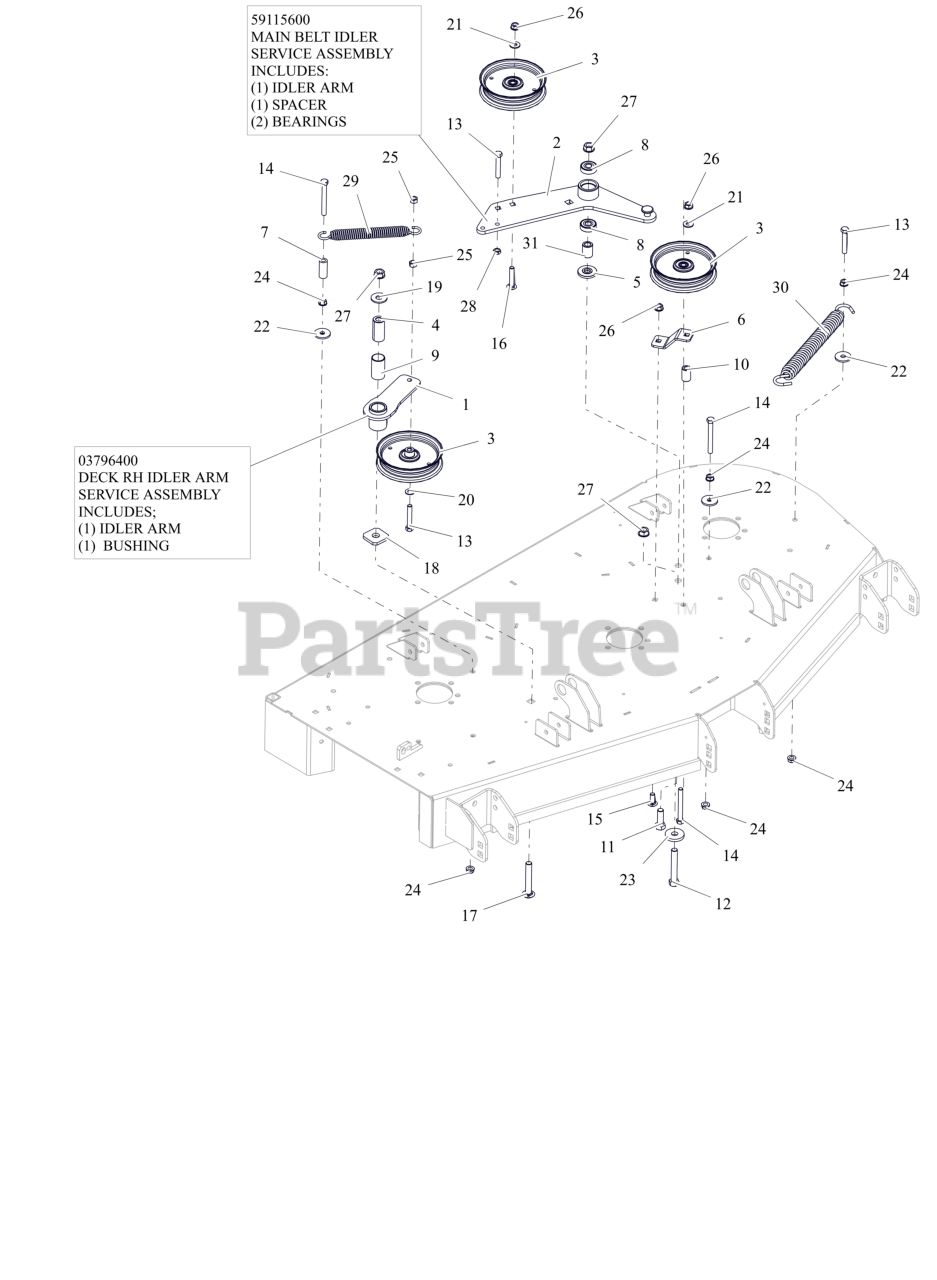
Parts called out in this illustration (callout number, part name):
1	WMT, IDLER ARM - BLACK
1	ASM, IDLER ARM (DECK)
2	WLDMT, DECK PTO IDLR ARM
2	ASSEMBLY, MAIN BELT IDLER
3	IDLER- FLAT - 5.00" X .75"
4	BSHG, SPCR .502X.997X2.03 PM
5	SPACER, IDLER ARM
6	PTO FIXED IDLER MTG BRKT-ORG
7	HOSE, .38 X 1.65
8	BRG-BALL .500X1.38X.437
9	BSHG, 1.00X1.125X1.937
10	BUSHING, SLV .380X.750X1.190
11	BLT,HEX .50-13X1.50 G5 ZCC
12	BLT,HEX .50-13X3.25 G5 ZCC
13	BLT,HEX .38-16X2.25 G5 ZCC
14	BLT, HEX .38-16X3.25 G5 ZCC
15	BLT,RHSSN .38-16X1.00 G5 ZCC
16	BLT,RHSSN.375-16X2.00 G5 ZCC
17	BTL,RHSSN .500-13 X 3.25 G5 ZCC
18	WSHR-FLT .640X1.75X.250
19	WSHR,FLT .563X1.375X.109 ZCC
20	WSHR,FLT .406X.812X.065 ZCC
21	WSHR,FLT .375X.875X.083 ZCC
22	WSHR,FLT .406X1.375X.135 ZCC
23	WSHR-FL-STL 0.557X1.625X0.25 ZCC
24	NUT, SPNLK-FLG .38-16 G5 ZCC
25	NUT-LK-CTR .38-16 ZC120
26	NUT-LK-CTR-FLG .375-16 GF ZCC
27	NUT-LK-CTR-FLG .500-13 GG ZCC
28	NUT-JAM .375-16 G2 ZCC
29	SPRING- EXTENSION
30	SPRING, EXTENSION
31	SPACER .510 X .867 X 1.1485
